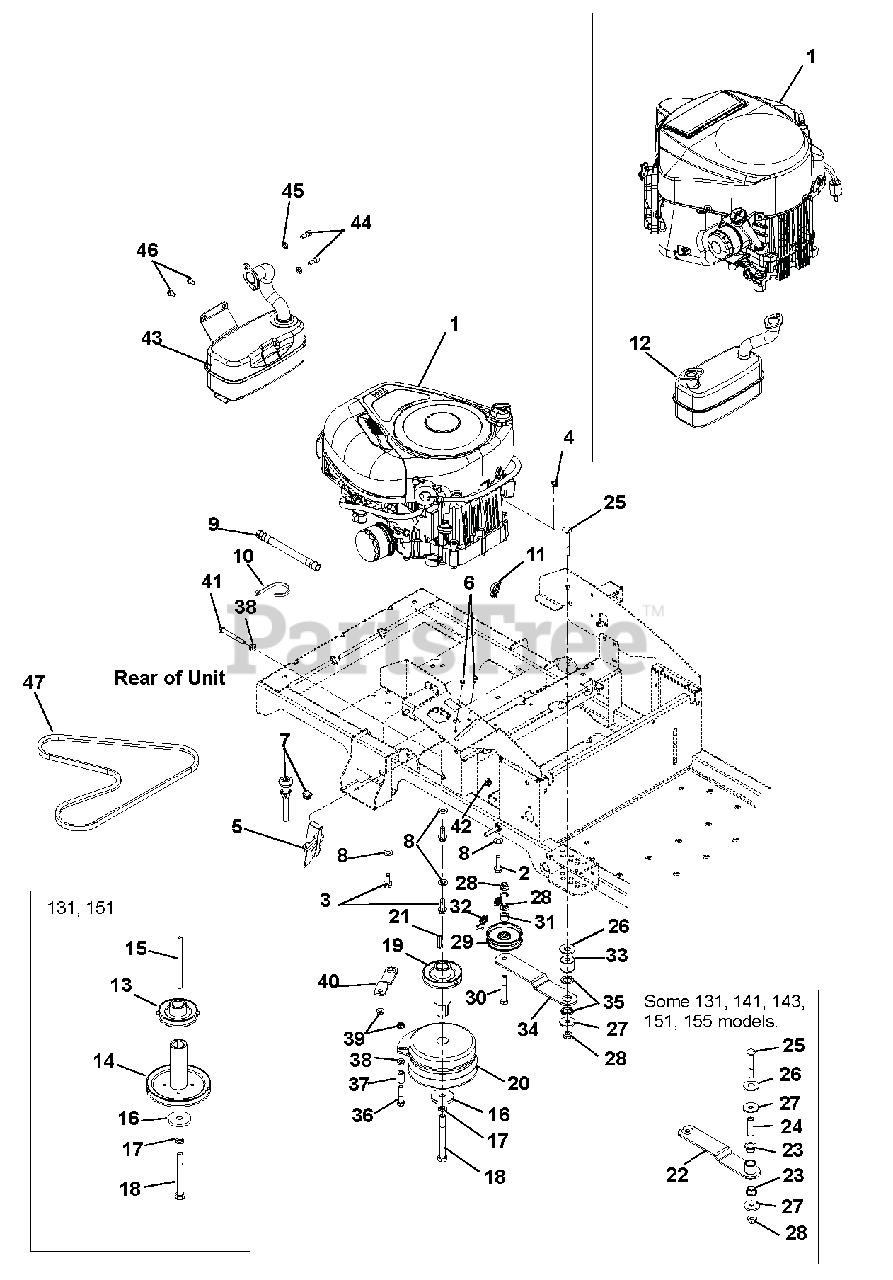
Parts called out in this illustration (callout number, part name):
1	ENGINE, 13.5HP BRIGGS IC
1	ENGINE, 18HP INTEK SINGLE
1	FR651-22 KAWASAKI TWIN ENGINE
1	ENGINE, 13.5HP B&S PP W/MUF
1	ENGINE, 16.5HP B&S PP W/O MUF
2	@SCR-TAP .38-16X1.25 HWH TR YZ
2	BLT-HEX.38-16X1.25FTHG5 EP30YZ
3	@SCR-TAP .38-16X1.00 HWH TR YZ
4	@NUT-LK-CTR-JAM .375-16 YWZC
5	THROTTLE/CHOKE CABLE
5	CABLE, THROTTLE
6	@SCR-TAP 10-24X.50 HWH TR YWZC
7	PLUG, 5/8" SQ BLACK (14-20GA)
7	CABLE, CHOKE (SNAP IN)
8	@WSHR-FL-STL.406X.812X.065 YWZ
9	OIL DRAIN HOSE
10	TIE WRAP
11	WIRE CLIP
12	MUFFLER, TWIN
13	WMT-SHEAVE, GROUND DRIVE
14	SHEAVE, PTO DRIVE
15	KEY-STR .25X.25X5.50
16	WSHR-FL-STL .469X2.00X.25 YWZC
17	@WSHR-LK .44X.109 REG YWZC
18	BLT-HEX .44-20X4.50 GR8 YWZC
19	WMT-PTO EXTENSION W/SHEAVE
20	CLUTCH, 105 FT*LB MONO POLE
21	KEY-SQ .25 X 1.25 X .25 SAE
22	WMT, IDLER ARM
23	BSHG-FLG, .625X.750X.500X1.00
24	SPACER, .375IDX.625ODX1.66 PM
25	@BLT-RDHDSQNK .38-16X2.75 G5YZ
26	@WSHR-FL-STL.563X1.38X.109YWZC
27	WSHR-FL-STL .406X1.375X.135 YZ
28	@NUT-LK-NYL-FLG .38-16 YWZC
29	PULLEY, ENGINE CLUTCH 03608
30	@BLT-HEX .38-16X2.75 GR5 YWZC
31	BSHG-SLV .391X.688X.52 PM
32	SPRING, EXTENSION
33	SPACER, GROUND DRIVE IDLER
34	IDLER ARM, GROUND DRIVE
35	BUSHING, IDLER ARM
36	SCR-CAP .31-18X1 3/4 S/HD YWZC
37	SPACER, RUBBER 5/16 IDX1.0 LG
38	@NUT-SPNLK-FLG .312-18 YWZC
39	@NUT-LK-TOP-FLG .31-18 YWZC
40	BRKT, CLUTCH STOP
41	@BLT-HEX .31-18X2.75 GR5 YWZC
42	@NUT-LK-NYL-FLG .31-18 YWZC
43	MUFFLER, B&S 500 BBZ
44	SCR-CAP .31-18X.75 S/HD
45	@WSHR-LK .31X.078 REG YWZC
46	SCR-TAP .25-20X.50 HWH TR YWZ
47	V-BELT, HA-RAW EDGE
